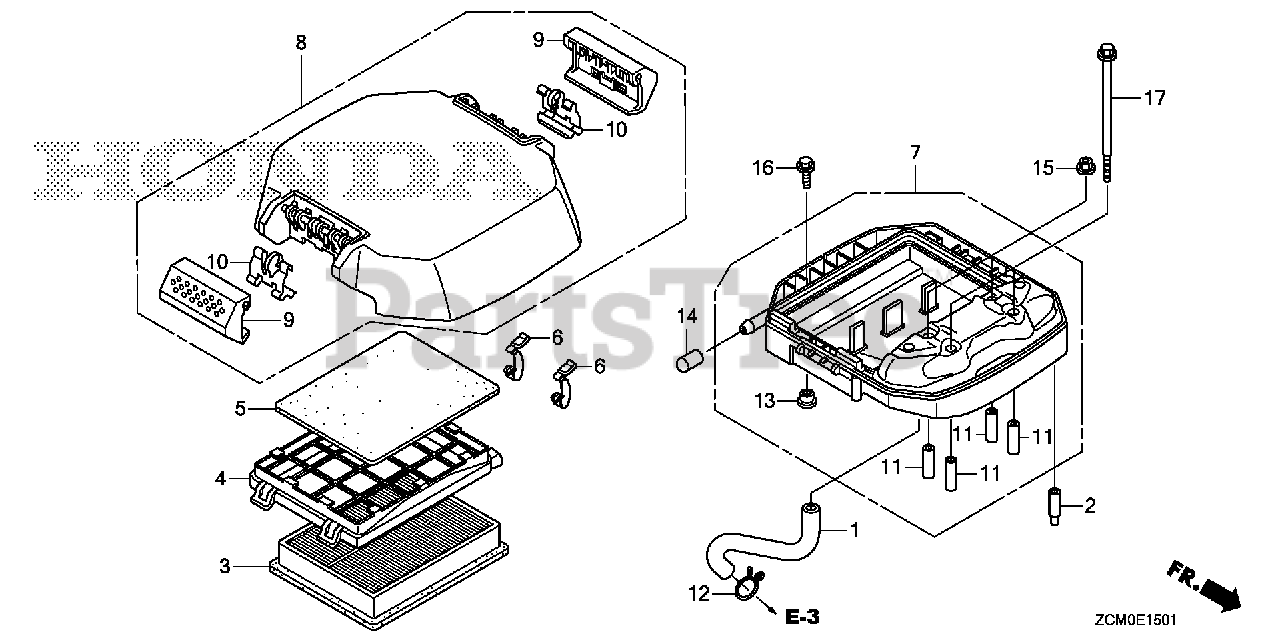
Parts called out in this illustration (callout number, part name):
1	TUBE, BREATHER
2	CAP, BOOST
3	ELEMENT, AIR CLEANER
4	HOLDER, ELEMENT
5	FILTER (OUTER)
6	CLIP, AIR CLEANER
7	HOUSING, AIR CLEANER
8	COVER, AIR CLEANER
9	KNOB, AIR CLEANER COVER
10	SPRING, AIR CLEANER HOUSING COVER
11	COLLAR, AIR CLEANER
12	CLIP, BREATHER TUBE
13	COLLAR, FAN COVER
14	CAP, SEALING
15	NUT, FLANGE (6MM)
16	BOLT, FLANGE (6X16)
17	BOLT, FLANGE (6X110)
